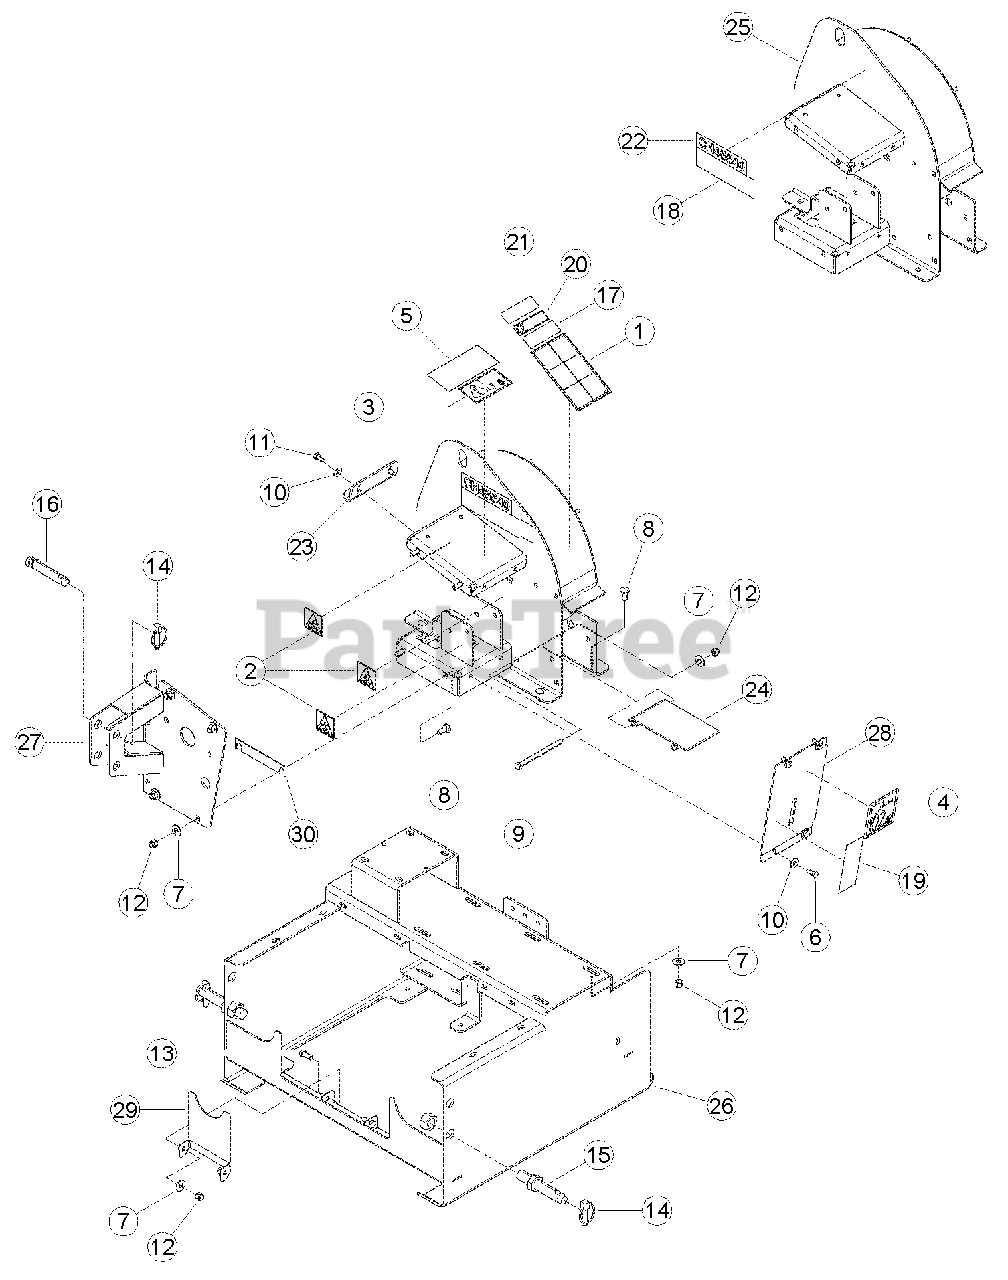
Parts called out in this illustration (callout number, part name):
1	DECAL, OPERATING INSTRUCTIONS ISO
2	DECAL, SHIELD DANGER ISO
3	DECAL, MAINTENANCE ISO
4	DECAL, 102 DB
5	DECAL, MUTILINGUAL MANUAL
6	BOLT, 5/16 X 3/4 HEX HD GR5 ZP
7	WASHER, 3/8 FLAT ZP
8	BOLT, 3/8 X 1 CRG GR5 NC ZP
9	BOLT, 3/8 X 5 HEX HD GR5 ZP
10	WASHER, 5/16 FLAT ZP
11	BOLT, 5/16 X 5/8 HEX HD GR5 ZP
12	NUT, 3/8 NE NYLOCK ZP
13	BOLT, 3/8-16 X 7/8 HEX HD GR5
14	PIN, 7/16 X 1-3/4 LYNCH
15	PIN, LIFT ARM 7/8 X 5 LONG
16	PIN, TOP LINK 3/4 X 4-1/2 LONG
17	DECAL, SERIAL NUMBER
18	DECAL, ECHO BEARCAT 6.82 X 1.90
19	DECAL, CHIPPER ENGAGEMENT
20	DECAL, 77454S INFORMATION
21	DECAL, ATLANTIC BRIDGE LTD INFO
22	DECAL, MODEL CH45540
23	GUIDE, BELT
24	WELDMENT, CHIP DEFLECTOR
25	WELDMENT, CHIPPER HOUSING
26	WELDMENT, CHIPPER 3 PT.
27	WELDMENT, BEARING SUPPORT
28	PANEL, SIDE
29	PLATE, PTO HOLDER
30	SHIM, 4-1/2 INCH CHIPPER
